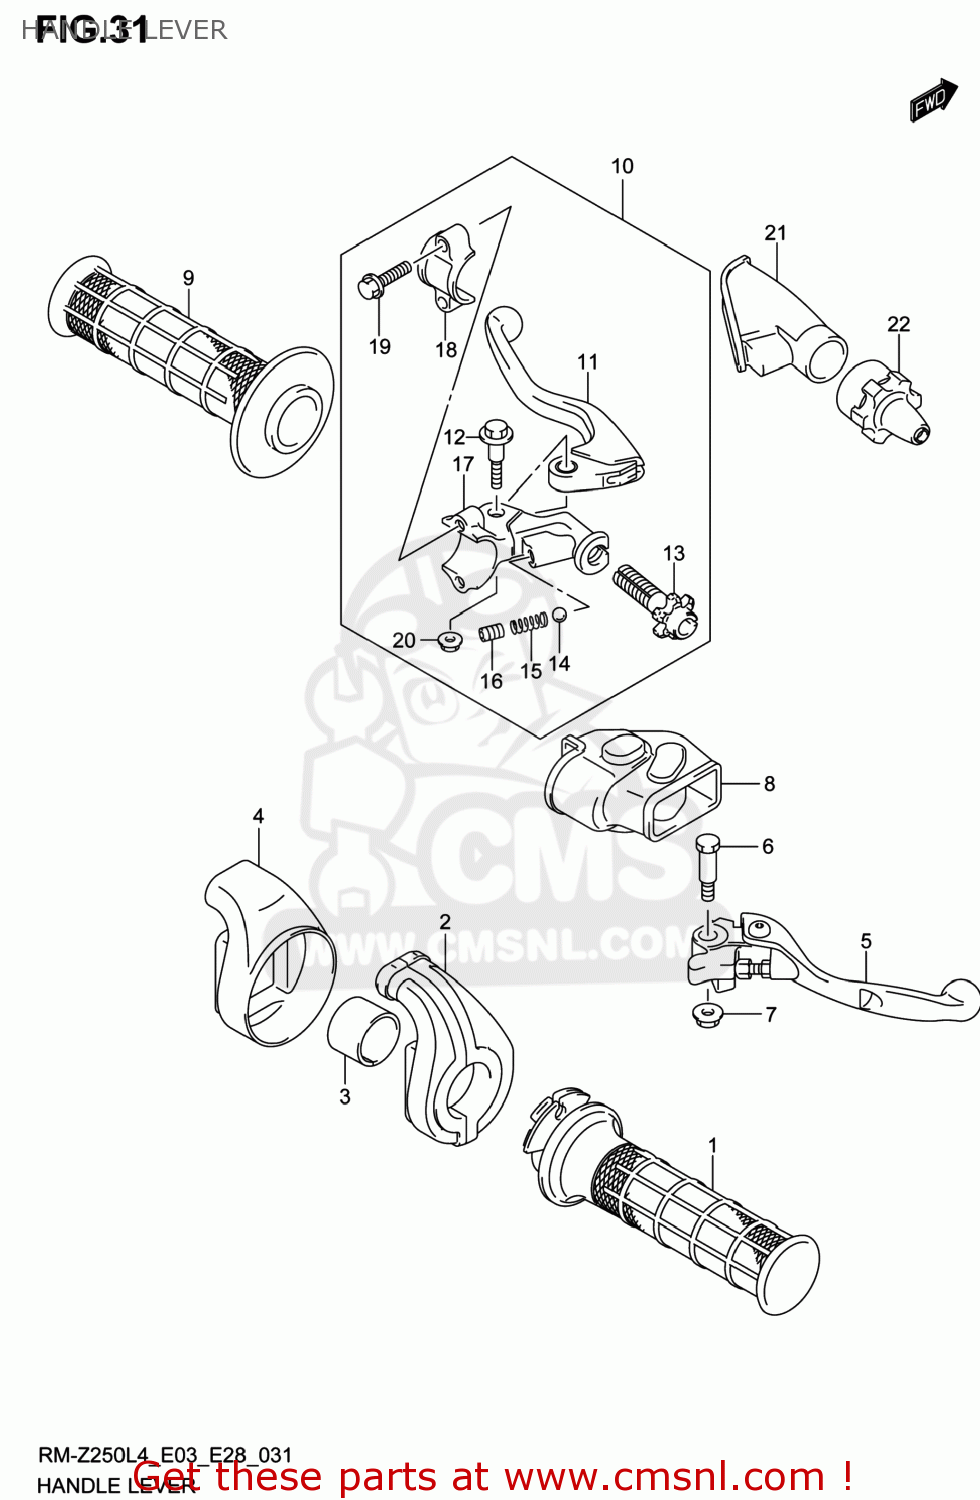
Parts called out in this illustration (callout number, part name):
1	GRIP,THROTTLE
2	CASE ASSY,THROTTLE
3	COLLAR,THROTTLE CASE
4	COVER,THROTTLE CASE
5	LEVER ASSY,BRAKE
6	BOLT,BRAKE LEVER
7	NUT
8	COVER,BRAKE LEVER
9	GRIP,L
10	LEVER ASSY,CLUTCH
11	LEVER,CLUTCH
12	BOLT
13	ADJUSTER,CLUTCH CABLE
14	BALL
15	SPRING
16	SCREW(6X8)
17	HOLDER,CLUTCH LEVER
18	BRACKET,CLUTCH LEVER HOLDER
19	BOLT,BRACKET
20	NUT
21	COVER,CLUTCH LEVER
22	COVER,CLUTCH ADJUSTER
